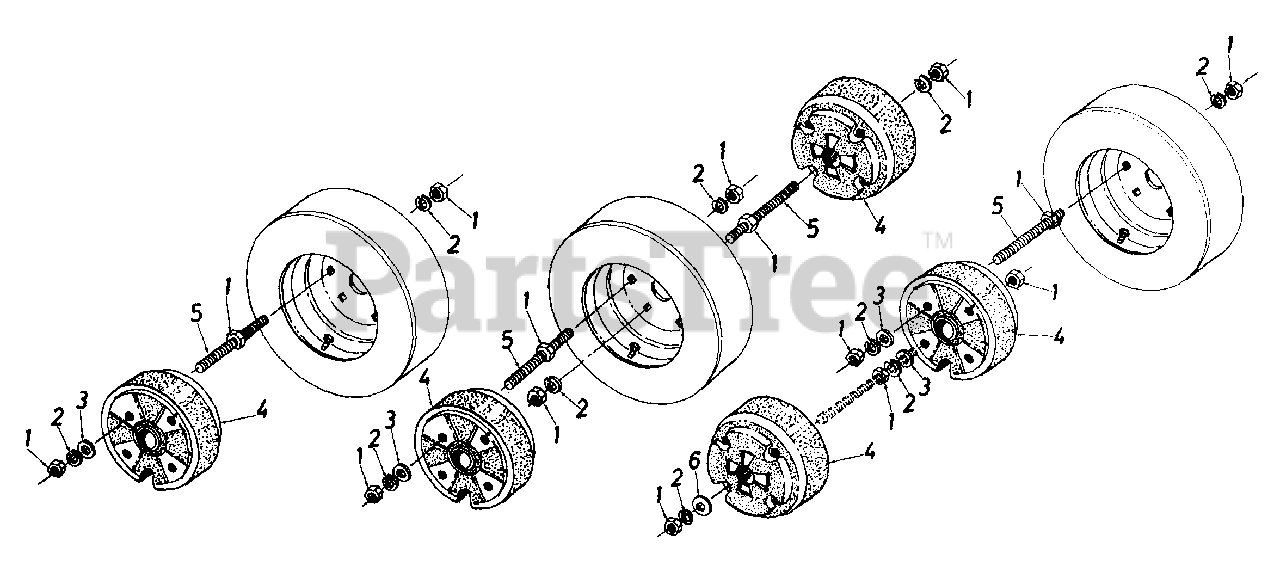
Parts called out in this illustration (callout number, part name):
1	Hex Nut 1/2-13 Thd.
2	Lock Wash. 1/2" I.D.
3	Fl-Wash. .53" I.D. x .93" O.D.
4	Wheel Weight
5	Rod Threaded 1/2-13 x 9.5" Lg.
6	Fl-Wash. .5" I.D. x 2.0" O.D.
